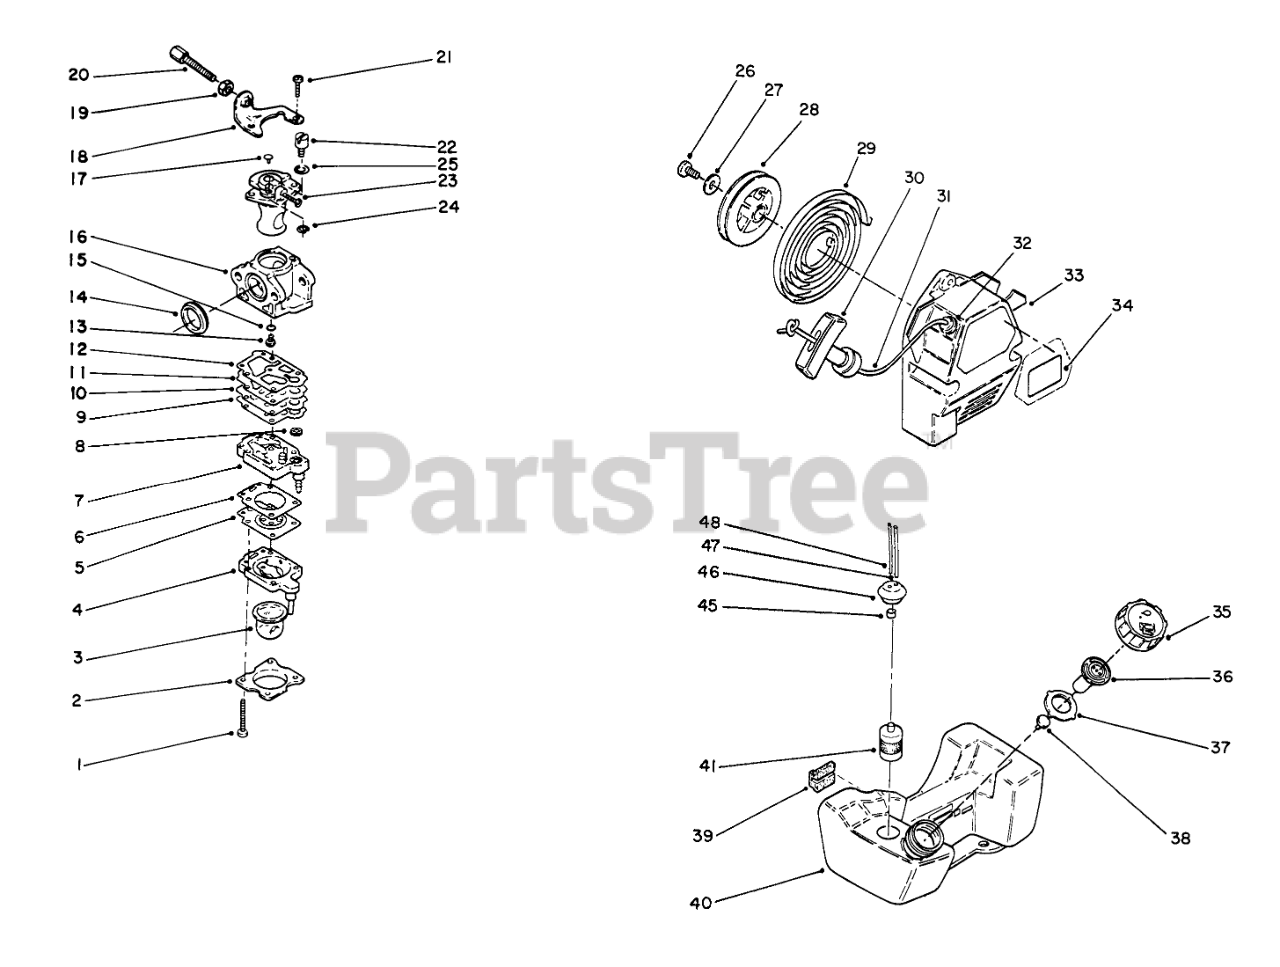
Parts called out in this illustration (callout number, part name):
1	SCREW
2	Cover-Primer
3	PRIMER PUMP
4	PRIMER BODY
5	DIAPHRAGM
6	DIAPHRAGM GASKET
7	Body Assembly-Pump(Incl. Ref. #8)
8	SCREEN
9	PUMP GASKET
10	Plate
11	DIAPHRAGM
12	DIAPHRAM GASKET
13	MAIN JET
14	RUBBER CARB GASKET
15	MAIN JET O-RING
16	Body-Carburetor (Ref.)
18	BRACKET
19	LOCKNUT
20	ADJUSTING SCREW
21	SCREW
22	Holder-Wire
23	THROTTLE VALVE
25	WASHER
26	SCREW
27	WASHER
29	SPRING
30	Knob-Starter
31	Rope-Recoil
32	GUIDE
33	RECOIL CASE
34	Decal-Toro
35	FUEL TANK CAP
36	BREATHER VALVE
37	PACKING
40	Tank Assembly-Fuel(Incl. Ref. #34-37)
41	FUEL FILTER
45	COLLAR
46	FUEL TANK GROMMET
47	FUEL TUBE
48	RETURN FUEL HOSE
